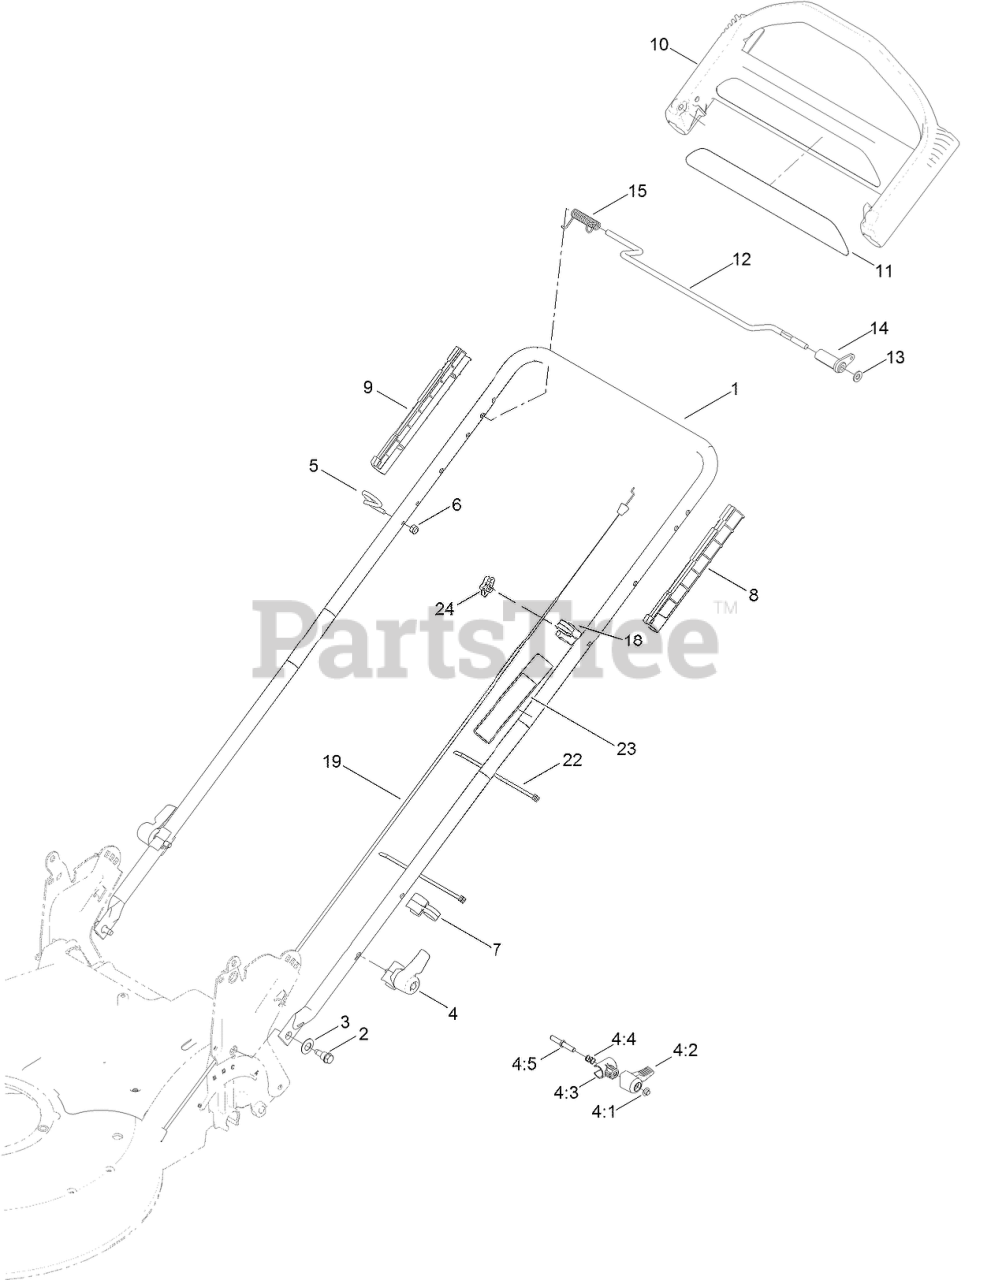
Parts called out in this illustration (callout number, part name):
2	BOLT-SHOULDER
3	WASHER-SPRING, CONICAL
4	QUICK RELEASE ASM
4:1	NUT-PUSH
4:2	LEVER
4:3	ANCHOR-SPRING
4:4	SPRING-COMPRESSION
4:5	ROD-RELEASE
5	GUIDE-ROPE
6	NUT-LOCK, NI
7	GUIDE-CABLE
8	GUIDE-LH
9	GUIDE-RH
10	HANDLE-CONTROL
12	BAR-CONTROL, TRACTION
13	WASHER-PLAIN
14	LEVER-TRACTION
15	Spring-Torsion
18	ANCHOR-CABLE
19	CABLE-TRACTION
22	TIE-CABLE
23	DECAL-TRACTION, ADJUST
24	KNOB-HANDLE, LOCKING
